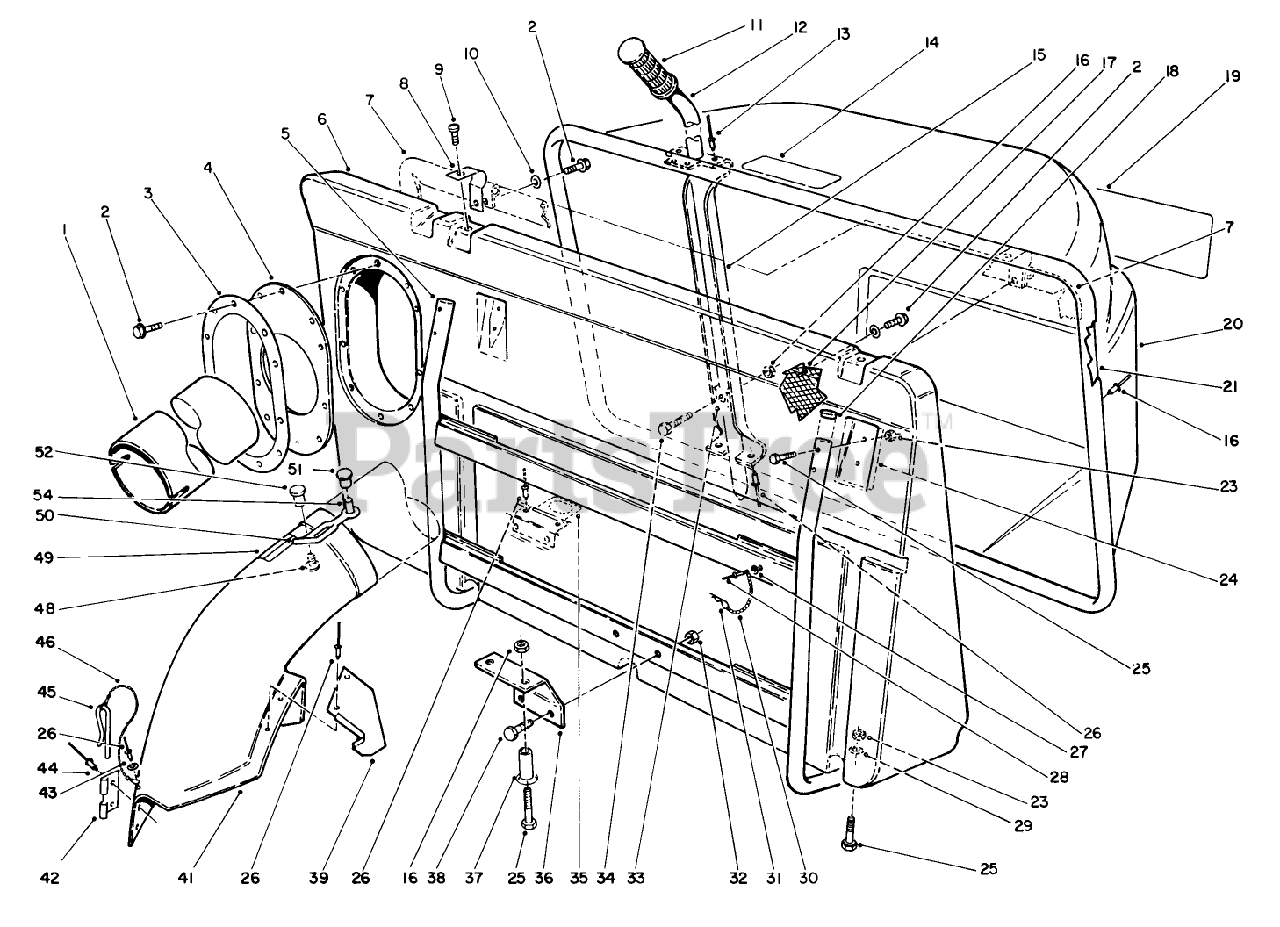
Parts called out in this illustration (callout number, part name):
2	SCREW-HWHTF
3	RING-RETAINING
4	RING-RETAINER, RUBBER
6	BAG-FRONT
7	SEAL-BAG
9	SCREW-HH
10	WASHER-FLAT
11	GRIP-HANDLE
12	HANDLE-DUMP
13	RIVET-POP
16	NUT-LOCK, NI
20	BASKET-GRASS
23	NUT-LOCK, NI
25	SCREW-HH
26	RIVET-BLIND
27	WASHER
29	WASHER-FLAT
31	PIN-HAIR
32	NUT-LOCK, NI
33	GUIDE-HANDLE, DUMP
34	SCREW-HH
38	SCREW-HH
39	CHUTE SUPT BRKT
42	BRACKET-MOUNTING, CHUTE
43	WASHER-PLAIN
44	RIVET-BLIND
45	PIN-LOCKING, CHUTE
46	LANYARD
50	RETAINER-DUCT
51	SPACER-INTERLOCK
54	FASTENER-PANEL
